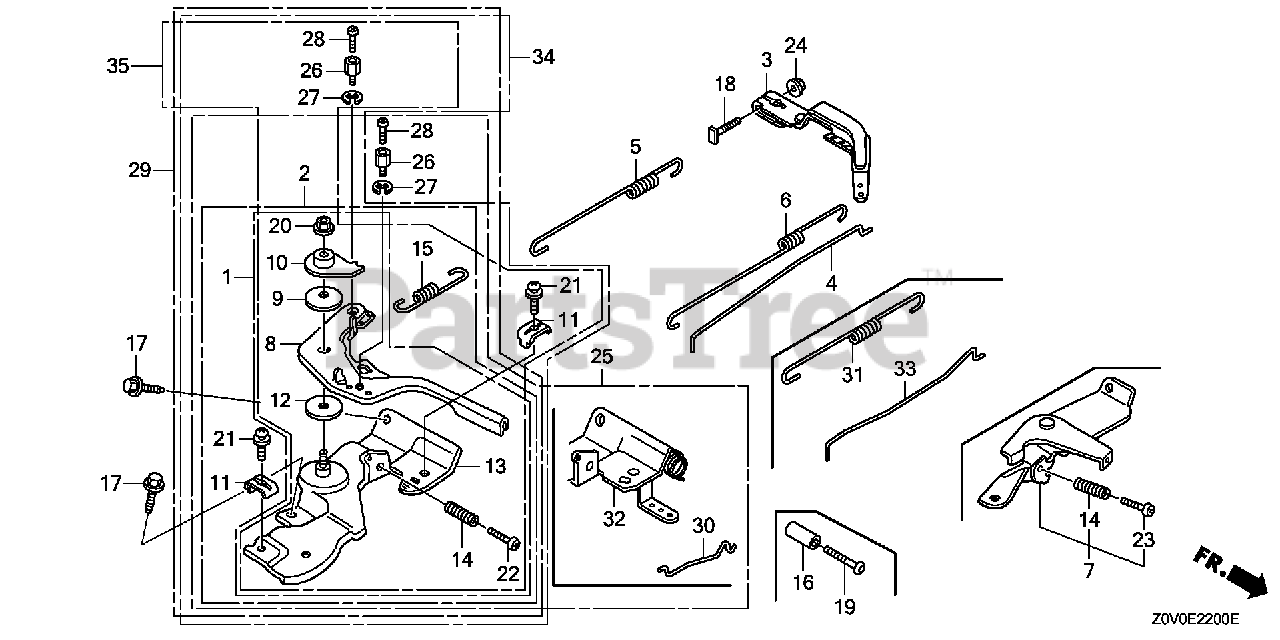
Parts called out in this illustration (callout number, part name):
2	CONTROL ASSY. (REMOTE)(COO)(FOR U.S.A.)
2	CONTROL ASSY. (REMOTE)
3	ARM, GOVERNOR
4	ROD, GOVERNOR
5	SPRING, GOVERNOR
6	SPRING, THROTTLE RETURN
8	LEVER, CONTROL
9	SPRING, LEVER
10	WASHER, CONTROL LEVER
11	HOLDER, CABLE
12	SPACER, CONTROL LEVER
13	BASE, CONTROL
14	SPRING, CONTROL ADJUSTING Use from Engine SN 2327377.
15	SPRING, CABLE RETURN
17	BOLT, FLANGE (6X12) (CT200)
18	BOLT, GOVERNOR ARM
20	NUT, SELF-LOCK (6MM)
21	SCREW, PAN (5X16)
22	SCREW, PAN (5X25)
24	NUT, FLANGE (6MM)
